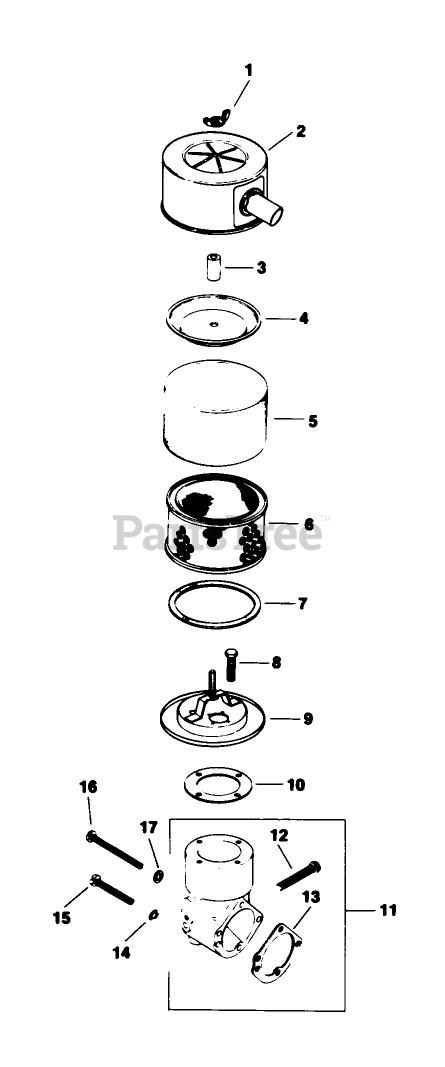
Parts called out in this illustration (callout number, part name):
1	Nut-Wing
2	Cover-Air Cleaner
4	Cover-Inner
5	Element
6	Element
7	Seal
8	Screw-H.C.
9	Base-Air Cleaner
10	Gasket-Air Cleaner
11	Kit-Air Intake Elbow
12	Screw-H.C
13	Gasket-Elbow
14	Washer
15	Screw-R.H.M.
16	Screw-R.H.M.
17	Washer
